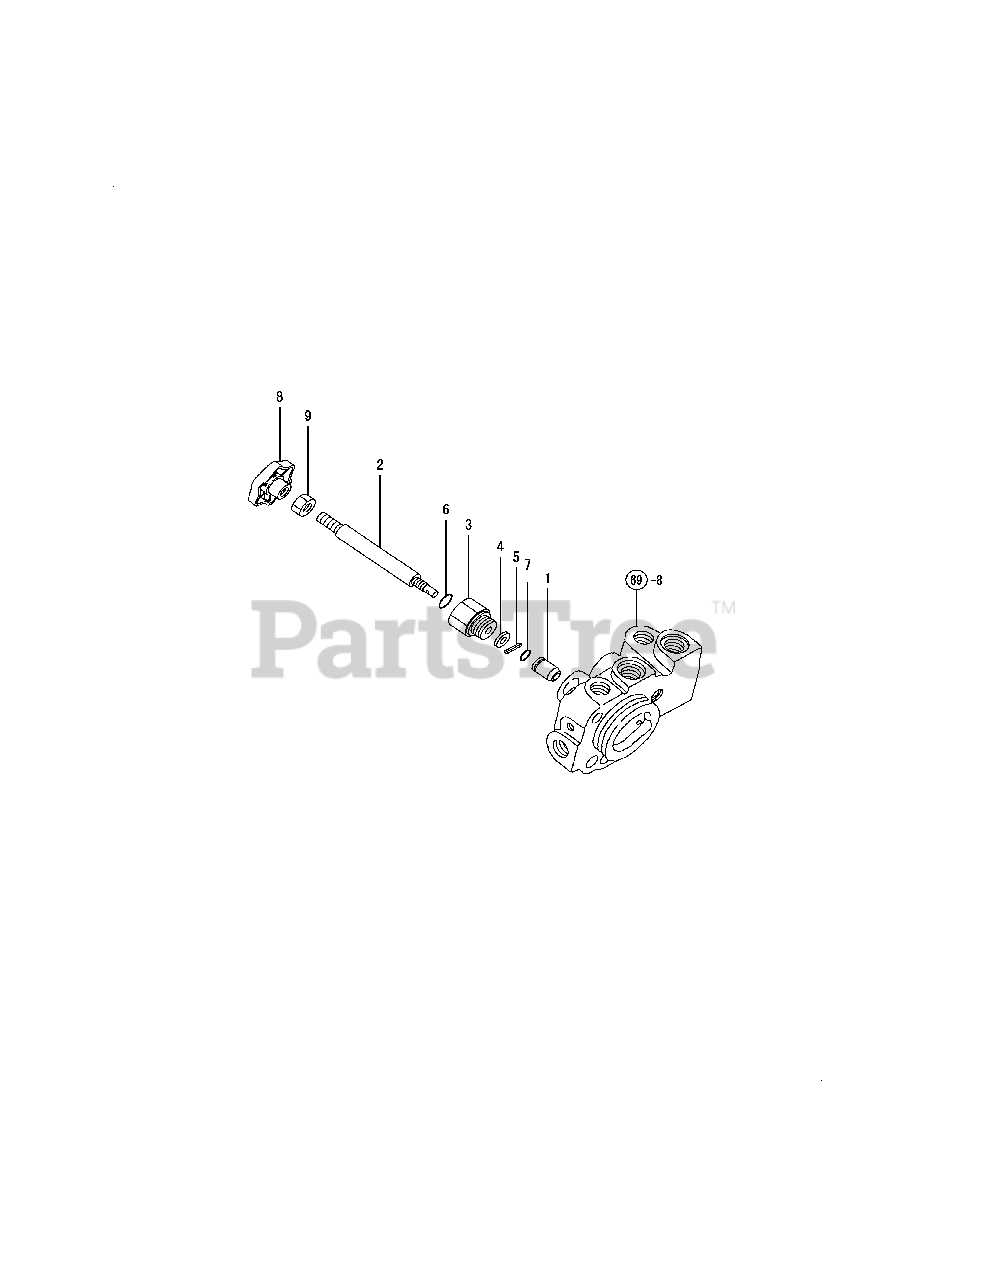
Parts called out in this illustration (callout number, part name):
3	HOLDER, VALVE (43)
5	SPRING PIN 4X10
6	O-RING 1A P 12.0
7	O-RING 1B P- 9.0
8	KNOB, STOP VALVE
